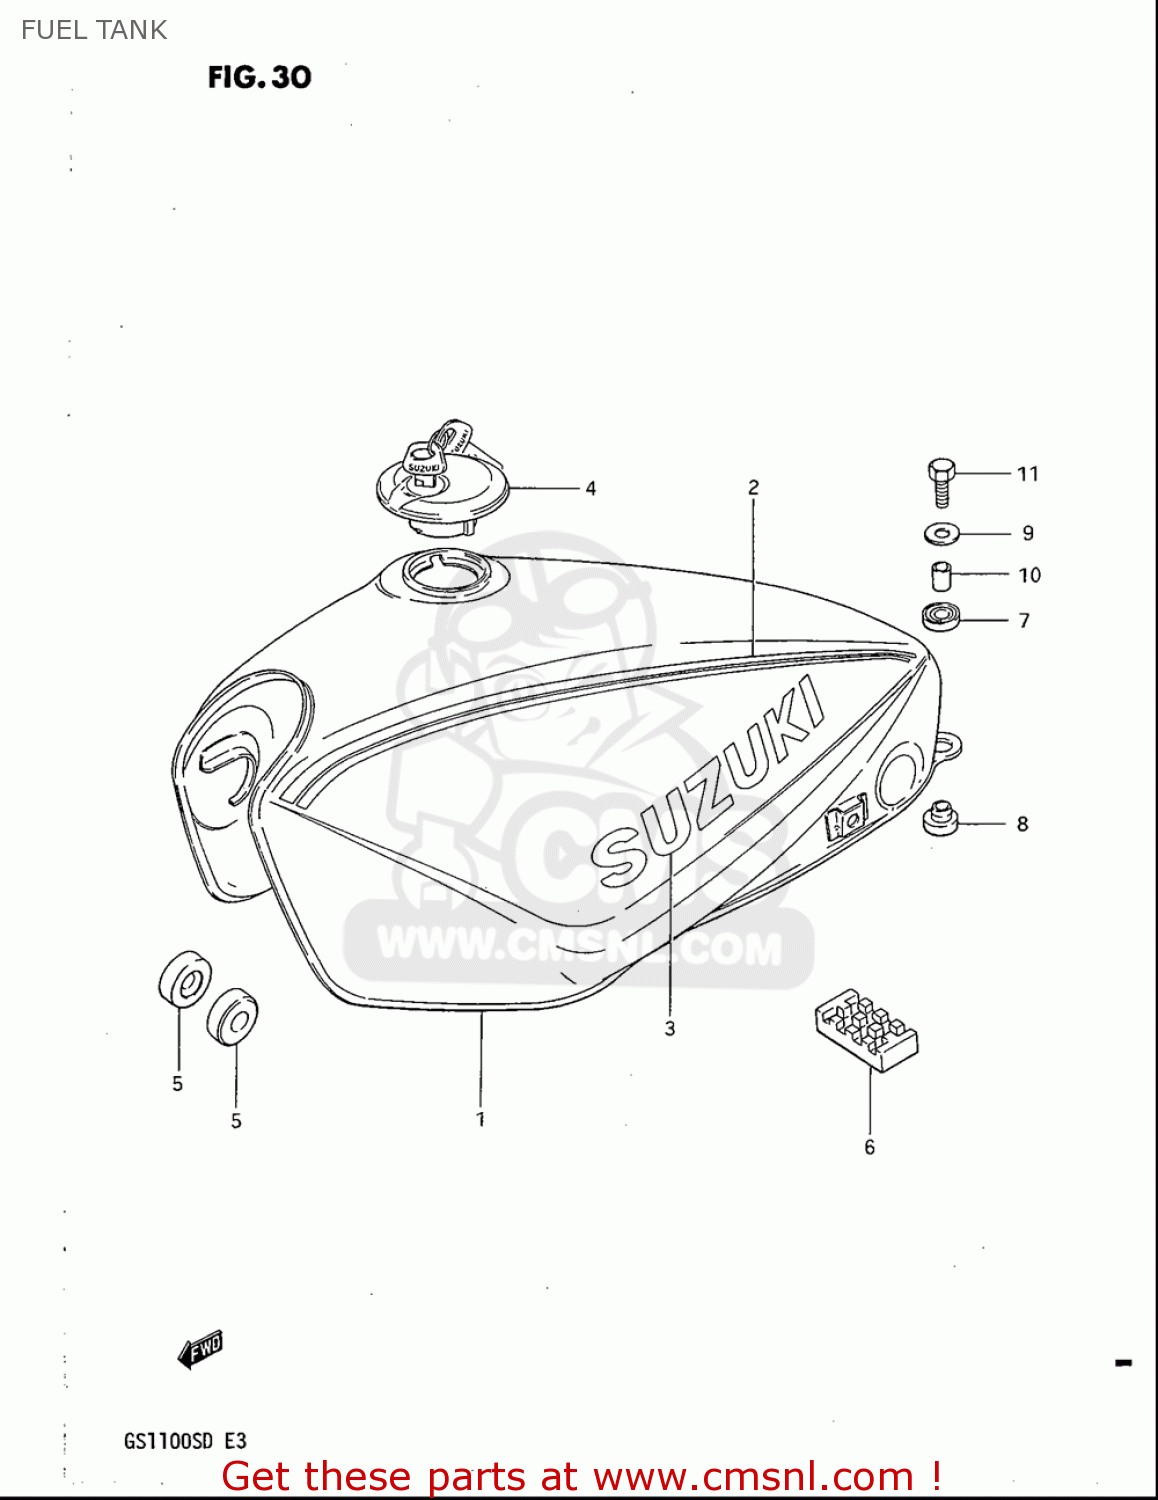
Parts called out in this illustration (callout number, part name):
1	TANK,FUEL(SILVER)
2	TAPE SET, FUEL TANK
3	EMBLEM(ORANGE)
4	CAP SET,FUEL TANK
5	CUSHION
6	CUSHION,FUEL TANK CTR
7	CUSHION
8	CUSHION
9	WASHER(6.5X24X1.6)
10	SPACER(6.5X9X18)
11	BOLT
